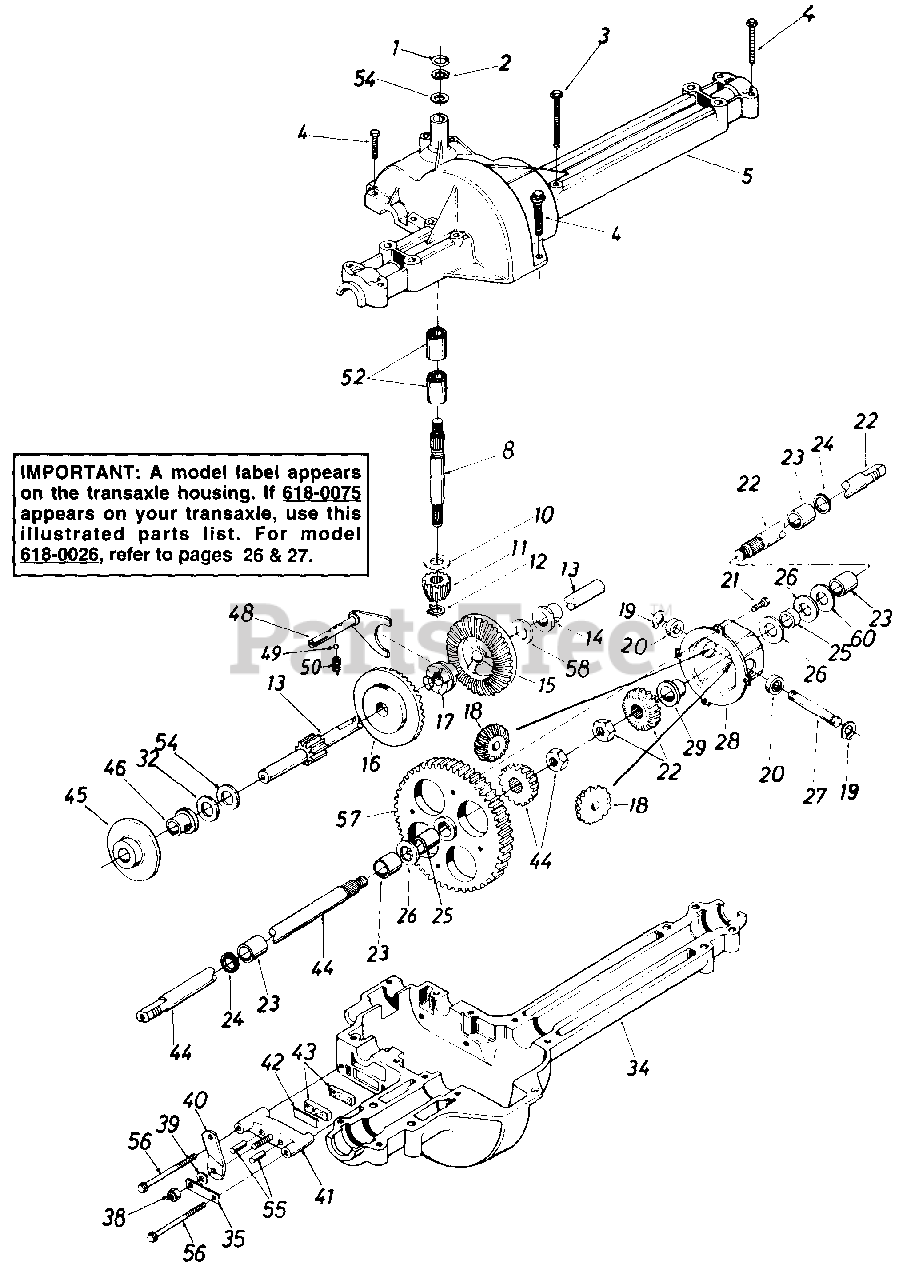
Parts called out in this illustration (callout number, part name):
2	Retaining - Ring
3	Hex Bolt 1/4-20 x 1.75" Lg.
4	Hex Tap Scr. 1/4-20 x 1.25" Lg.
5	Upper Housing
10	Thrust Washer 5/8" I.D. x 1.25" O.D.
11	Pinion Input 14T
12	Retaining Ring
13	Drive Shaft - L.H. Brake
14	Flange Brg. 5/8" I.D. x 3/4" Lg.
15	Bevel Gear 42T - Small I.D.
16	Bevel Gear 42T - Large I.D.
17	Clutch Collar
18	Miter Gear 15T (H.D.)
19	Snap Ring
20	Thrust Bearing
21	Pan Head Scr. 1/4-20 x .50" Lg. w/Patch
22	Axle R.H. Ass'y.
23	Sleeve Bearing 3/4" I.D. x 1.0" Lg.
24	Oil Seal 3/4" I.D.
26	Fl-Wash. .760" I.D. x 1.5" O.D.
28	Differential Can Ass'y.
32	Thrust Wash. 5/8" I.D. x 1" O.D. x .025" Thk.
34	Lower Housing
35	Anti-Rotation Brkt.
38	Hex Nut 5/16-24 Thd.
39	Fl-Wash. .344" I.D. x .875" O.D.
40	Actuating Arm
41	Brake Yoke
42	Puck Plate
43	Brake Puck
44	Axle L.H. Ass'y.
45	Brake Disc
46	Flange Bearing 5/8" I.D. x 15/16" Lg.
48	Shift Fork Ass'y.
49	Ball Detent .250" Dia.
50	Spring Detent
52	Needle Brg. 5/8" I.D. x 1/2" Lg.
54	Fl-Wash. 5/8" I.D. x 1" O.D. x .020 Thk.
55	Actuating Pin 5/16" Dia.
56	Hex Wash Hd. Self-Tap Scr. 1/4-20 Thd.
57	Differential Gear 58T
58	Fl-Wash. 5/8" I.D. x 1" O.D. x .020 Thk.
60	Fl-Wash. .76" I.D. x 1.5" O.D. x .010" Thk.
